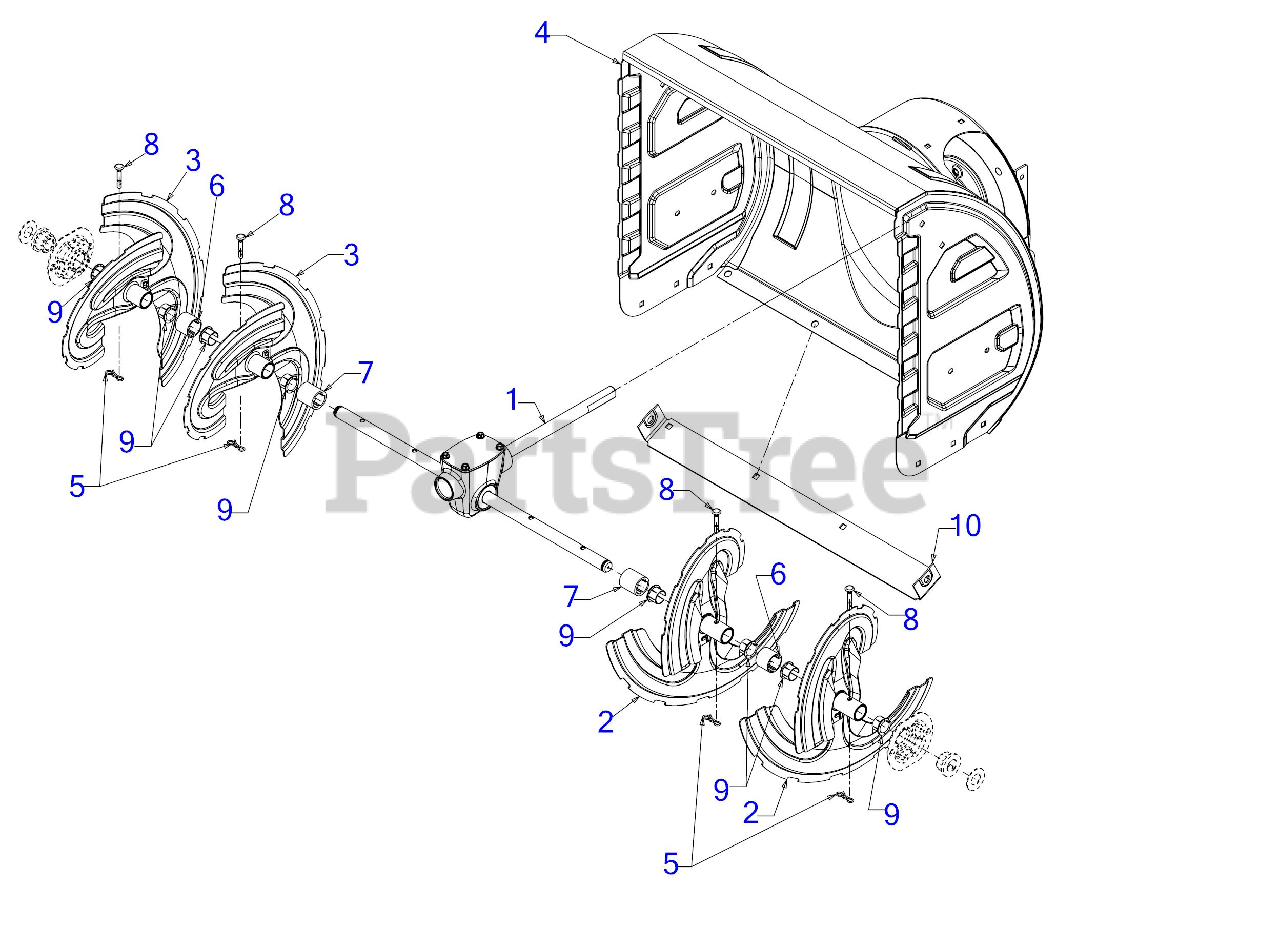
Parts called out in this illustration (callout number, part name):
1	24" AUGER GEARBOX ASSEMBLY
2	AUGER ASSEMBLY (LH)
3	AUGER ASSEMBLY (RH)
4	24" AUGER HOUSING ASSEMBLY
5	BOW TIE COTTER PIN 1/4-5/16
6	SPACER 1.25OD x .75ID X1.00 LG
7	SPACER 1.25OD x .75ID x 1.312 LG
8	SHEAR PIN .25 x 1.50 GR2
9	FLANGE BUSHING
10	24" SHAVE PLATE
